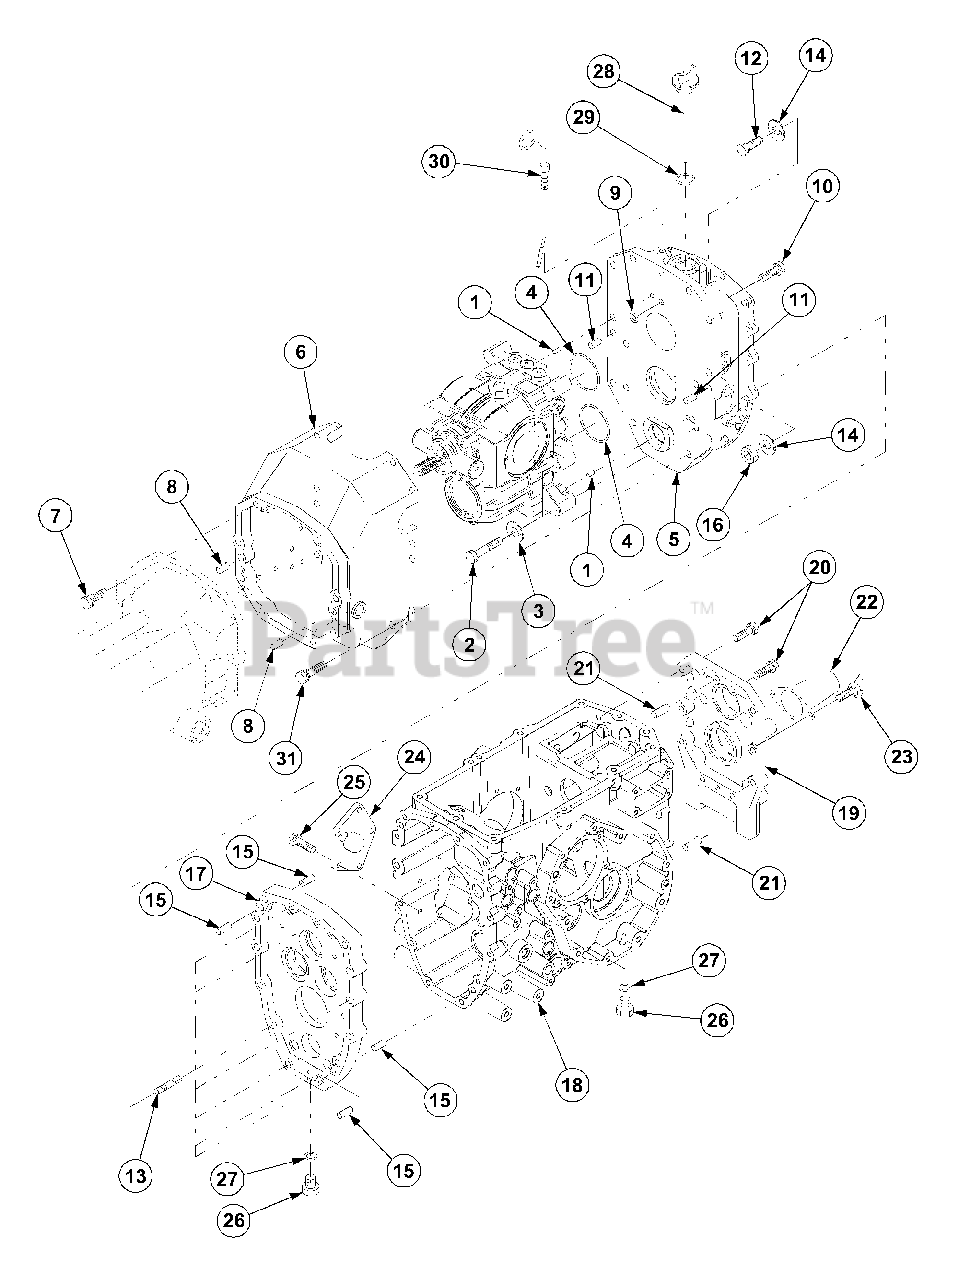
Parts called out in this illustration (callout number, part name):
3	Washer,Spring
7	Bolt,w/Washer
10	Bolt,w/Washer
14	Washer,Spring
17	Holder,Bearing
18	Housing,Diff
20	Bolt,w/Washer
25	Bolt,w/Washer
31	Bolt,w/Washer
